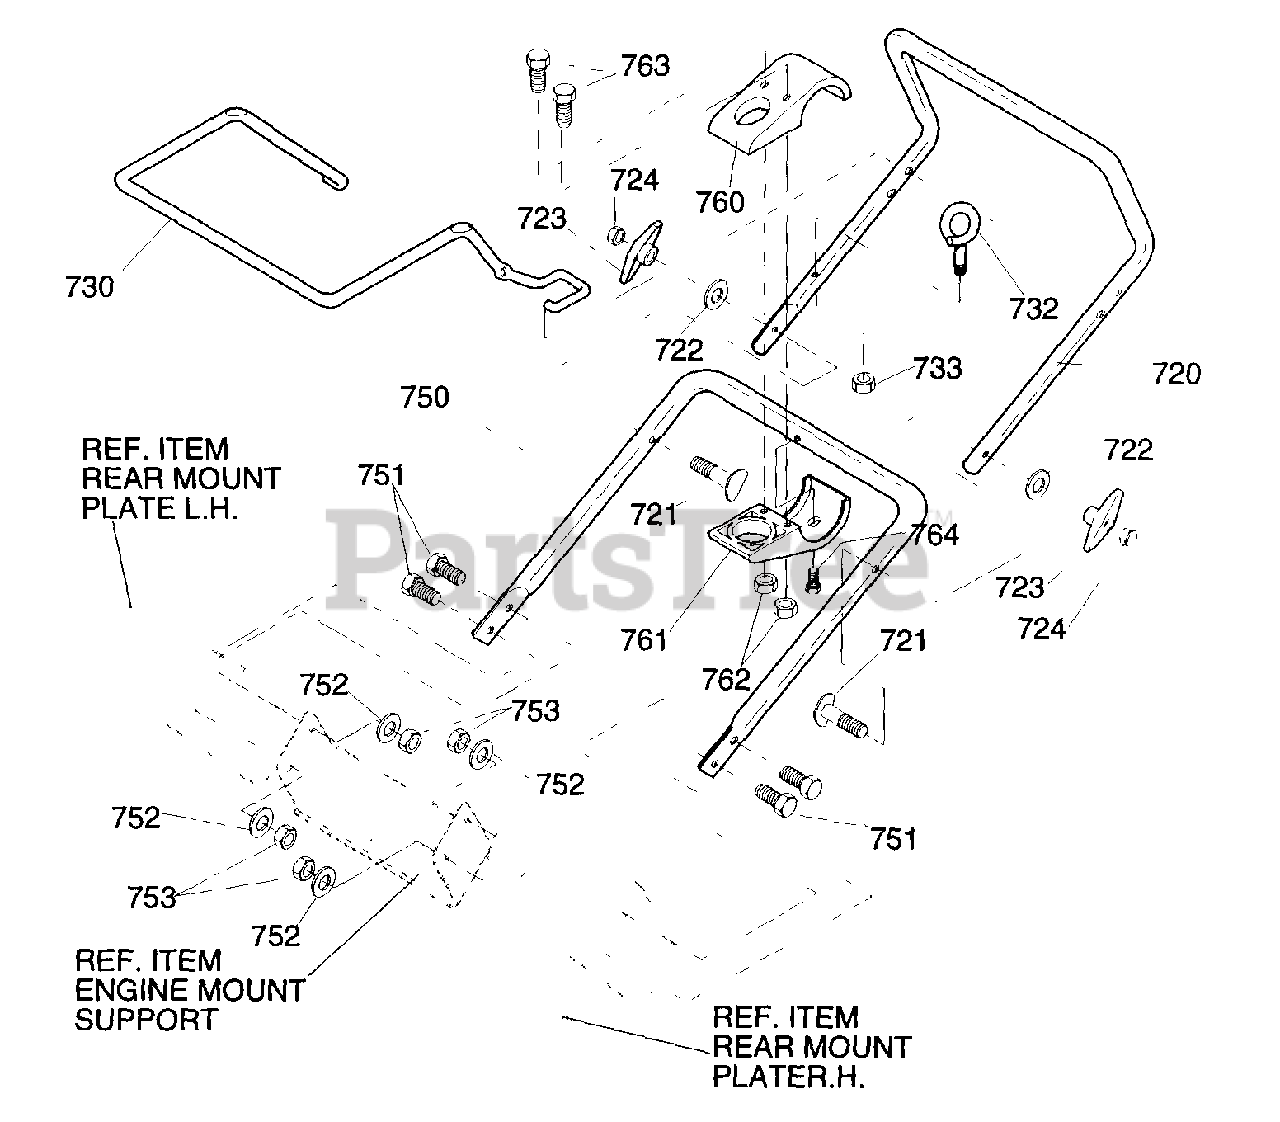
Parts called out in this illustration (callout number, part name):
720	HANDLE & FOAM ASSY
721	BOLT, 5/16-18X2.00 CUH
722	FORMED WASHER
723	KNOB, T 2/BLADE
724	NUT, 5/16-18 REGHEX
730	CONTROL DRIVE BAR
732	ROPE GUIDE
733	NUT, 5/16-18 RGNXCTRLK
750	LOWER HANDLE
751	SCREW 5/16-18X.75
752	FLATWASHER
753	NUT, 5/16-18 REGHXCTRLK
760	BRKT, HALF CHUTE CRANK
761	BRKT, HALF CHUTE CRANK
762	NUT #10-24 HEXNYLLK
763	SCREW 010-24X1.00
764	SCREW 1/4-20X.63 TAP.
